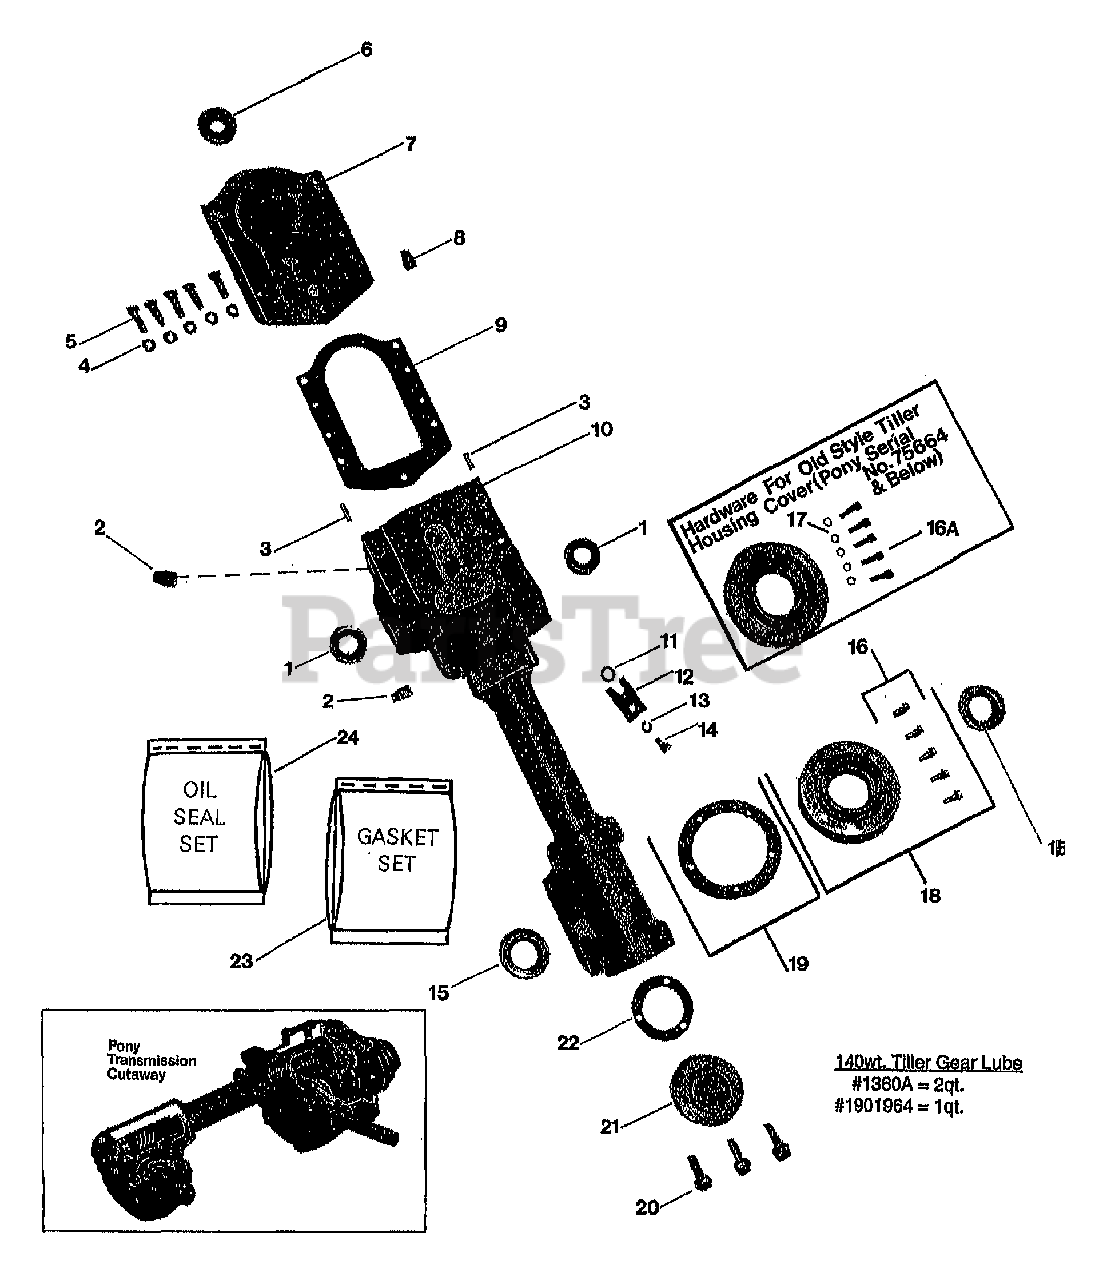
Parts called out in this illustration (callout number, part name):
1	SEAL-OIL WHEEL SHAFT
2	PLUG-PIPE 3/8"
3	PIN-DRIVE .25 X .75 (INCL. WITH TRANSMISSION CASE PART NO. 20330)
4	WASHER-LK .312 ZP
5	SCR-HH 5/16-18X1.0 G5 ZP
6	SEAL-OIL .75 ID (INSTALLS IN COVER)( FORMERLY #611)
7	COVER-TRANS MACH
8	PLUG-PIPE 1/4 NPT
9	GASKET-TRANS COVER
10	CASE-TRANS (WITHOUT COVERS, SHAFTS, GEARS. CALL FACTORY FOR SERVICE HELP)
11	RING-O .625 X .438 (SEE PAGE 16, INDEX 13)
12	PLATE-FRICTION (SEE PAGE 16, INDEX 17)
13	WASHER-LK .25 ZP (SEE PAGE 16, INDEX 19)
14	SCR-HH 1/4-20X.5 GR5 YEL
15	SEAL-OIL TILLERSHAFT
16	SCR-HH 1/4-20X.625
16A	SCR-HXSKT 1/4-20X.625
17	WASHER-LK .25 HI-COLLAR
18	COVER-W/SCRS(TLR) (9780)
19	GASKET-TILLER COVER (AR)
20	SCR-HFLK 1/4-20X.875
21	CAP-REAR #1115
22	GASKET-BRG COVER (AR)
23	TRANS GASKET SET-PONY (AR)
24	OIL SEAL SET-PONY (AR)
